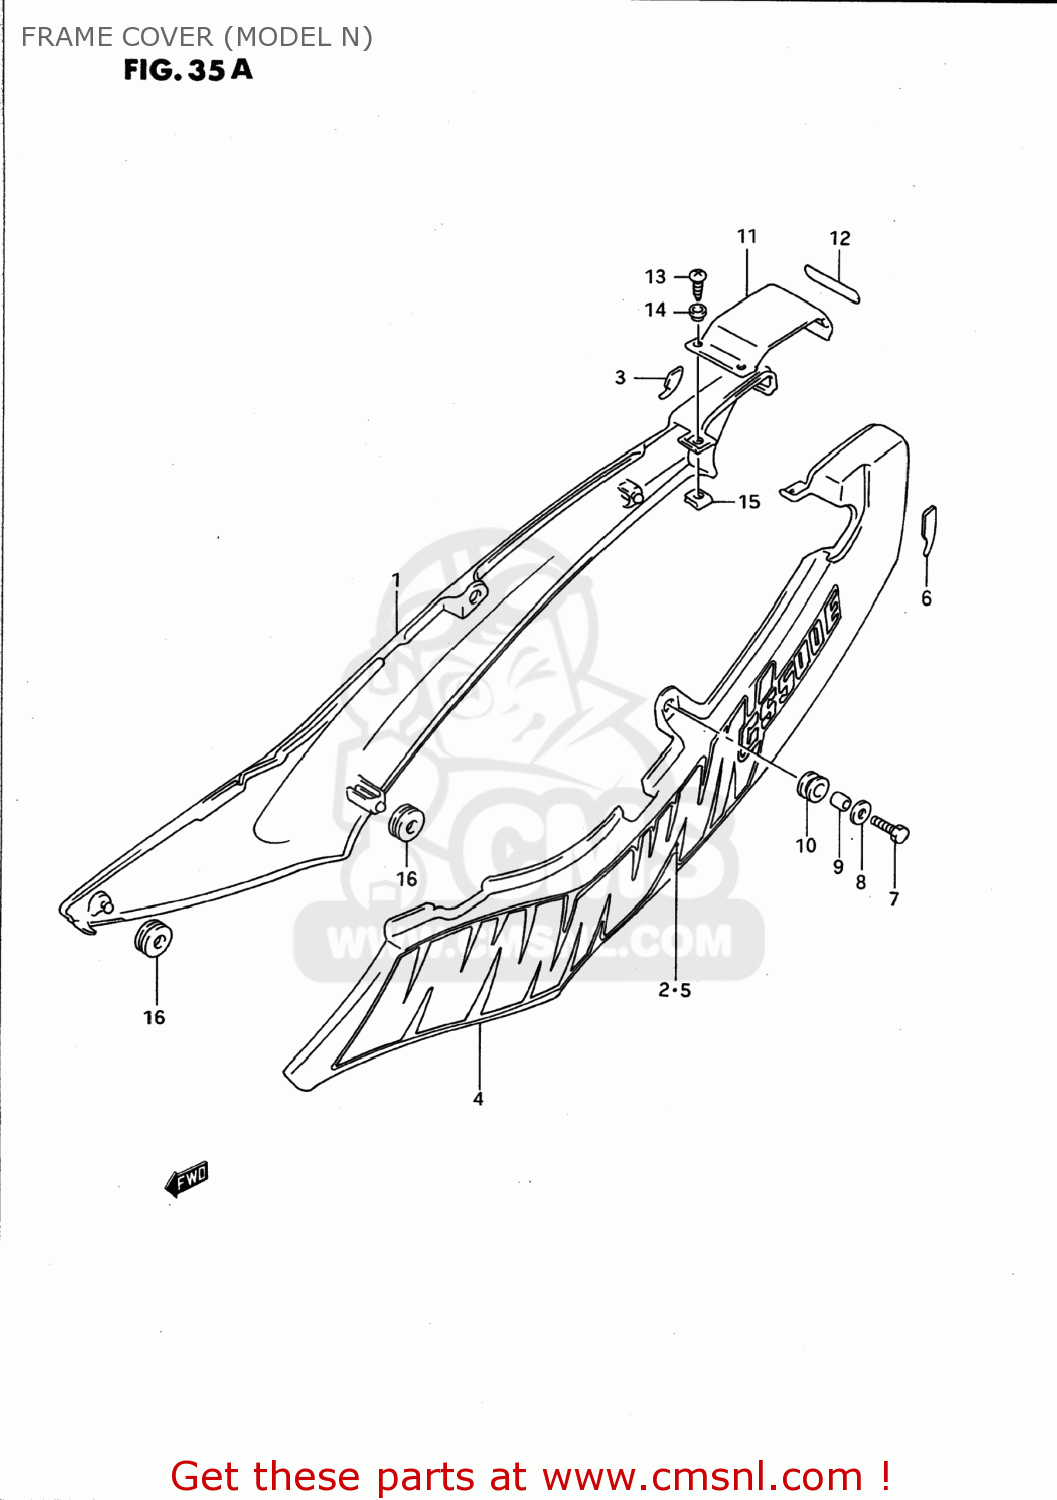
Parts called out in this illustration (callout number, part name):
1	COVER COMP,FRAME,RIGHT
2	TAPE SET,FRAME COVER STRIPE
3	PROTECTOR,FRAME COVER,R
4	COVER COMP,FRAME,LEFT
5	TAPE SET,FRAME COVER STRIPE
6	PROTECTOR,FRAME COVER,L
7	BOLT(6X20)
8	WASHER
9	SPACER (6.1X9X9)
10	CUSHION
11	COVER,FRAME,CENTER
12	EMBLEM,SUZUKI(WHITE)
13	SCREW
14	WASHER(5.2X14X1.5)
15	NUT
16	CUSHION
